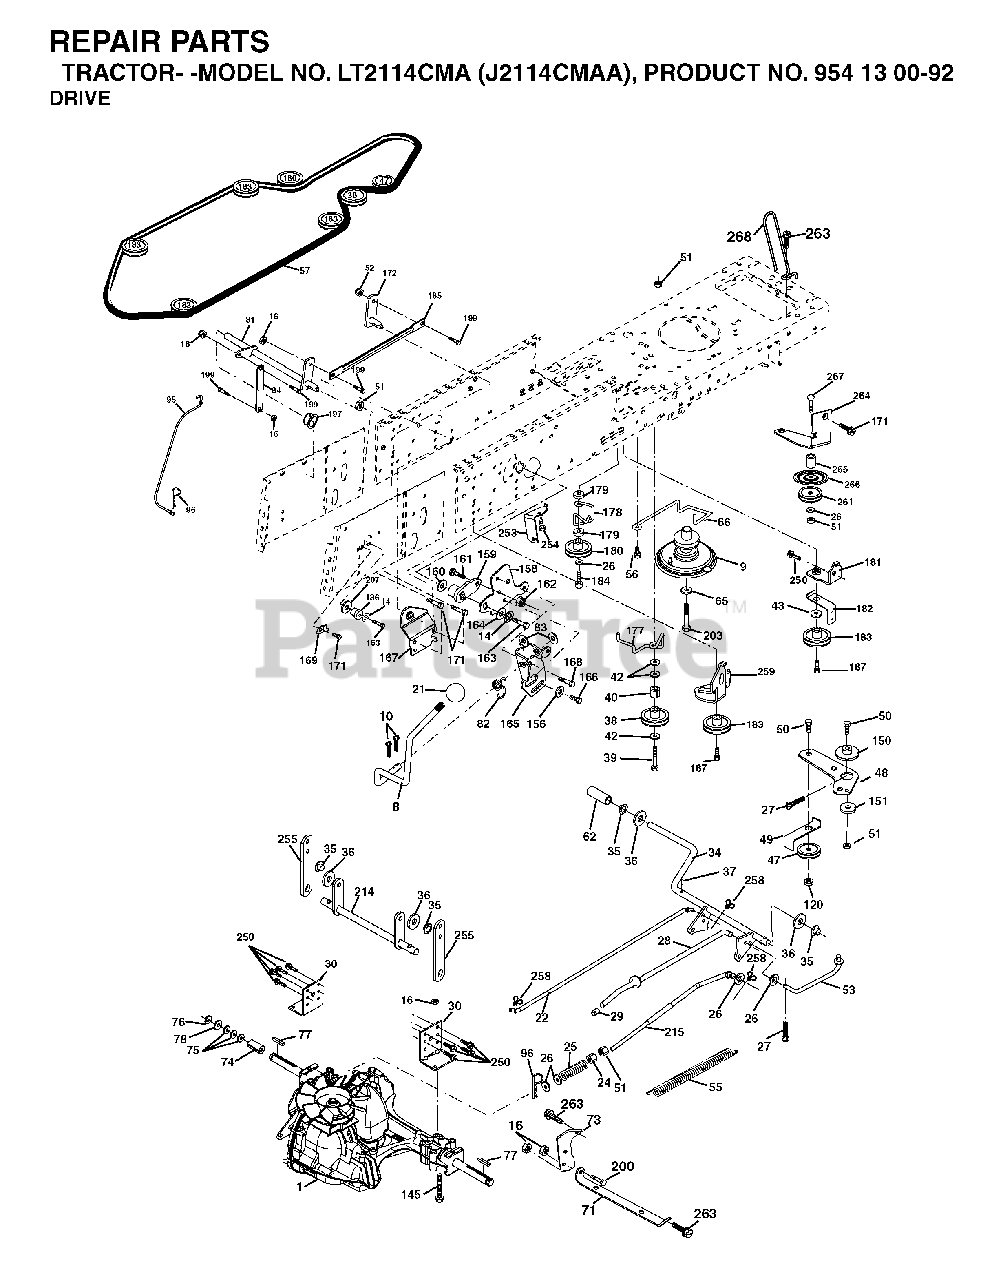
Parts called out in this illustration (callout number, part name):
8	ROD SHIFT
10	PIN COTTER
14	LOCKWASHER
16	NUT.71038.31-18.HEX.NYLOCK
21	KNOB.DELUXE.(PISTOL.GRIP).BLAC
24	NUT
25	SPRING ROD LT
27	COTTER PIN
28	ROD, PARKING BRAKE
29	PLUNGER CAP
30	BRKT, TRNSXLE MNT 20"
34	SHAFT, FOOT PEDAL
35	BEARING.NYLON
36	WASHER LT
37	DRIVE PIN
38	PULLEY.FLAT
42	WASHER
47	IDLER PULLEY
48	BELLCRANK, CLUTCH
49	RETAIN BELT
50	BOLT.3/8-16X1.50
51	LOCKNUT
52	LOCKNUT
53	LINK, CLUTCH LT
55	SPRING, RETURN LT
56	SCREW.3/8-16
62	PEDAL COVER T
65	LOCKWASHER
66	KEEPER BELT ENGINE
71	STRAP TORQUE LH HYDRO
73	STRAP TORQUE RH HYDRO
74	SPACER AXLE
76	E-RING LT
77	SQUARE KEY
81	SHAFT ASSY
82	SHIFT SPRING
83	WASHER
96	RETAINER M
120	NUT LOCK FLG 3/8-16 UNC
145	BOLT HEX 5/16-18 GR 5
150	BUSHING.BELLCRANK.GRD.DR
151	WASHER 12/32X2X10GA
156	WASHER.SRRTD.5/16
158	BRACKET
159	HUB
161	BOLT
162	NUT.CROWNLOCK.1/4
165	RP BRACKET
167	BRACKET
168	BOLT.SHOULDER.5/16-18X
169	PLATE.FASTENING.CROSS.SHAFT
180	PULLEY.FLAT.IDLER
184	SCREW.HXWSH.3/8
187	BOLT.5/16-18X1.25
197	NYLINER SNAP 5/8" ID
199	BOLT SHOULDER 5/16-18 UNC
200	BOLT
207	WASHER NYL
250	SCREW 3/8-16X3/4
254	SCREW 3/8-16X1
258	CLIP RETAINER
261	FLAT IDLER PULLEY
263	SCREW, 3/8-16X3/4
265	SPACER IDLER
